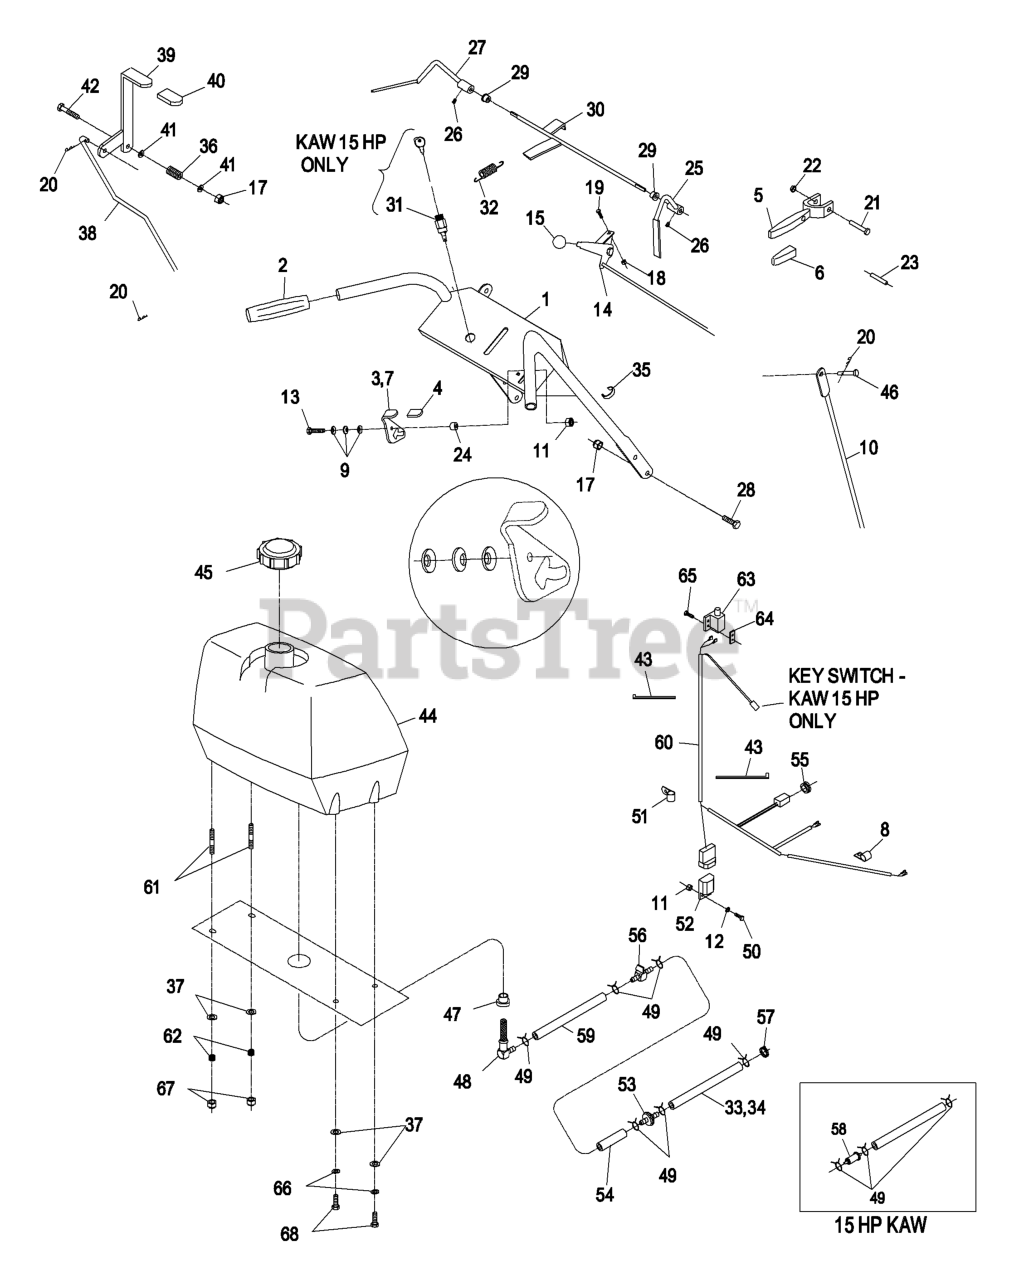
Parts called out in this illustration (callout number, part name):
1	KIT,HANDLE/DECALS METRO
4	GRIP-LATCH
5	DRIVE LEVER ASM
6	GRIP-LEVER, DRIVE
8	CLIP-LOOM
9	WASHER-SPRING
10	LINKAGE-WHEEL, DRIVE
11	NUT-LOCK, NI
12	WASHER-FLAT
13	SCREW-HH
14	CABLE-CONTROL, THROTTLE
15	KNOB-BALL
16	TIE-CABLE
17	NUT-LOCK, NI
18	NUT-LOCK, NI
19	BOLT-CARR
20	PIN-COTTER
21	PIN-LEVER, DRIVE
22	NUT-PUSH
23	PIN-ROLL
25	LEVER-RH
26	SCREW-SET
27	LEVER-LH
28	SCREW-HH
29	BUSHING-NYLON
30	WLD,ROD OPC
31	SWITCH & KEY (INCLUDES NU
32	SPRING-EXTENSION
33	HOSE-FUEL
34	HOSE-LINE, FUEL
35	CLIP-CABLE
36	SPRING-COMPRESSION
37	WASHER-PLAIN
38	LINKAGE-BLADE, UPPER
40	GRIP-LEVER
41	WASHER-FLAT
42	SCREW-HH
43	TIE-PLASTIC
45	CAP-FUEL
46	PIN-CLEVIS
48	ELBOW-TANK, FUEL
49	CLAMP
50	SCREW-HH
51	CLIP-LOOM
52	MODULE-INTERLOCK
54	HOSE-LINE, FUEL
55	GROMMET
56	VALVE-FUEL
57	CLAMP-HOSE
58	Kawasaki P/N 41019-1055
59	HOSE-FUEL
61	STUD
62	SPRING-TANK, FUEL
63	SWITCH-OPEN, NORMALLY
64	PLATE-TAPPED
65	SCREW-PPH
66	WASHER-LOCK
67	NUT-LOCK, NI
68	SCREW-HH
